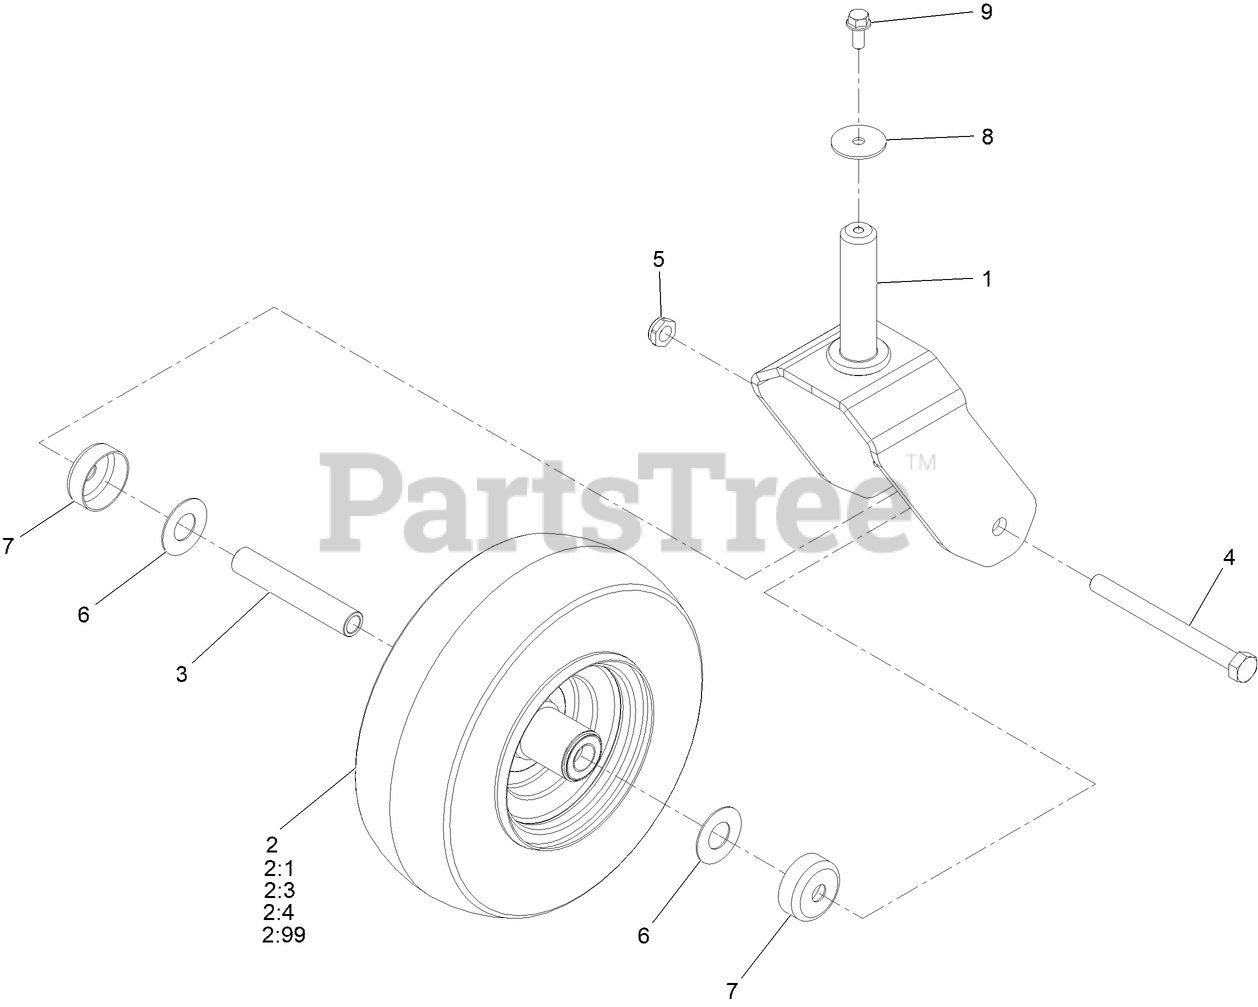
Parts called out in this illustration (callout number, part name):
2	TIRE ASM
2:3	Stem-Valve
2:4	BEARING
2:99	TUBE-INNER
3	SPACER-SPANNER
4	SCREW-HH
5	NUT-LOCK, NI
7	GUARD-SEAL
8	WASHER-FLAT
9	SCREW-HHF
